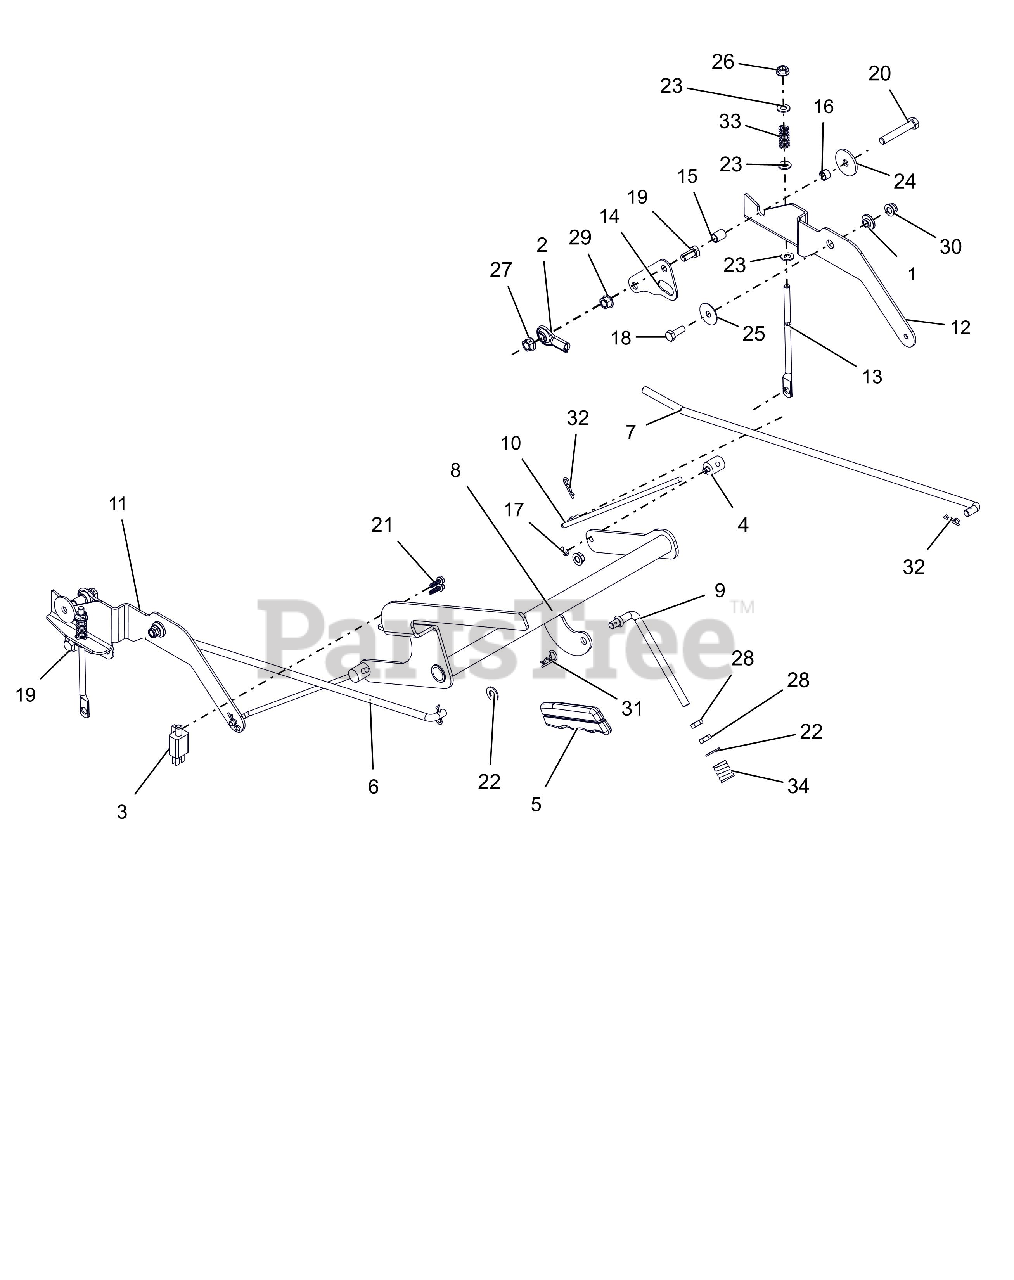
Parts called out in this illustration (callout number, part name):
1	BSHG, FLG .325X.499X.26X.88
2	ROD END, .38 RH
3	SWITCH- DOUBLE POLE N.O./N.O.
4	TRUNION, 1/4-20
5	GRIP, PARKING BRAKE (YELLOW)
6	STEERING, LINKAGE RH
7	STEERING, LINKAGE LH
8	WLDMT, BRAKE LEVER
9	LINK, OVER CENTER, PARKING BRK
10	LINK, BRAKE ARM
11	INTERLOCK, RH BRAKE LINK
12	INTERLOCK, LH BRAKE LINK
13	LINK, BRAKE COG
14	PLATE, TRANSAXLE ADAPTOR
15	SPCR, SLV .385X.500X.652
16	SPCR, SLV .385X.500X.350
17	RG-RTNG-EXT .250X.025
18	BOLT-HEX.31-18X.875 YWZC GR5
19	@BLT-HEX .38-16X.75 GR5 YWZC
20	@BLT-HEX .38-16X2.25 GR5 YWZC
21	SCR-TAP #12X.75 BOSS INDHXHD
22	@WSHR-FL-STL.406X.812X.065 YWZ
23	@WSHR-FL-STL.344X.688X.065YWZC
24	WSHR-FL-STL .380X1.50X.125YWZC
25	WSHR-FL-STL .347X1.254X.048YWZ
26	@NUT-LK-CTR-FLG .31-18 YZ GR F
27	NUT-LK-CTR-FLG .38-16 YWZC
28	NUT-HEX-JAM .375-16 YWZC
29	@NUT-LK-TOP-FLG .38-16 YWZC
30	@NUT-LK-NYL-FLG .31-18 YWZC
31	PIN-HAIR CTR .09 X 1.50 YWZC
32	PIN-HAIR INT .08X.18X1.18 YWZC
33	SPRING, COMPRESSION
34	SG-COMP .187X.56X1.62
